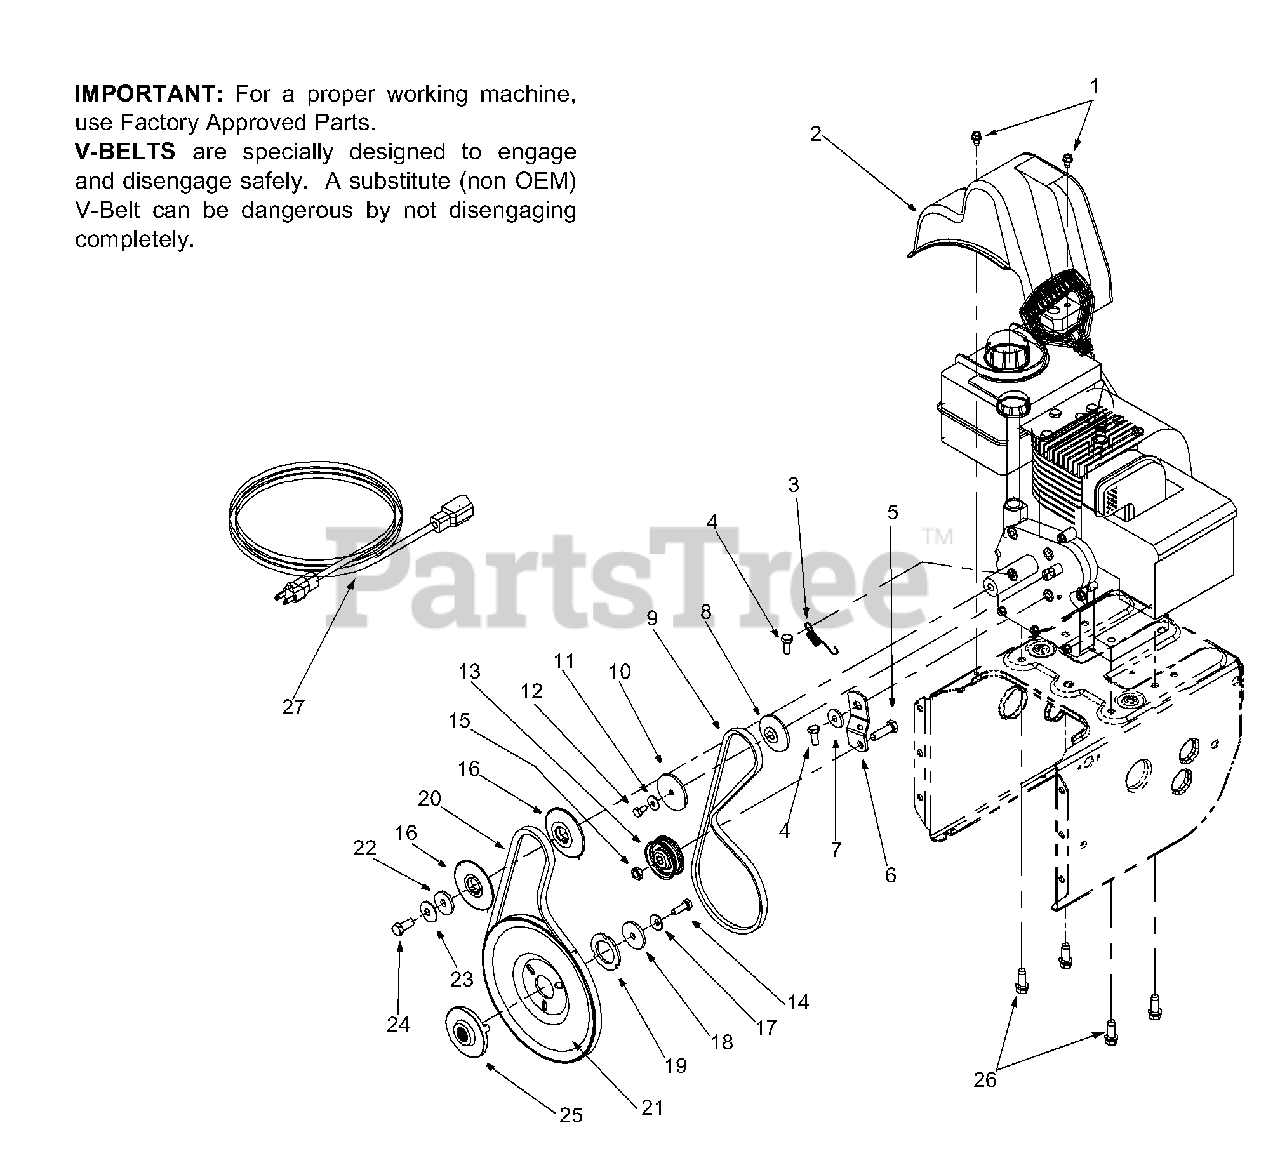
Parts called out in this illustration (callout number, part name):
1	Hex Washer Screw 1/4-20 x.625
2	Belt Cover
3	Extension Spring
4	Hex Screw 5/16-24 x .75
5	Hex Cap Screw 3/8-16 x 1.25
8	Pulley Half
9	V-Belt
10	Pulley Half
11	Bell Washer
12	Hex Cap Screw 1/4-28 x .50
13	Flat Idler
14	Lock Cap Screw 5/16-24
15	Lock Jam Nut 3/8-16
16	Pulley Half
17	Bell Washer
18	Flat Washer
19	Washer
20	Belt
21	Auger Pulley
22	Flat Washer
23	Bell Washer
24	Hex Cap Screw 3/8-24
25	Pulley
26	Hex Washer Screw 3/8-16 x 1.0
27	Extension Cord
